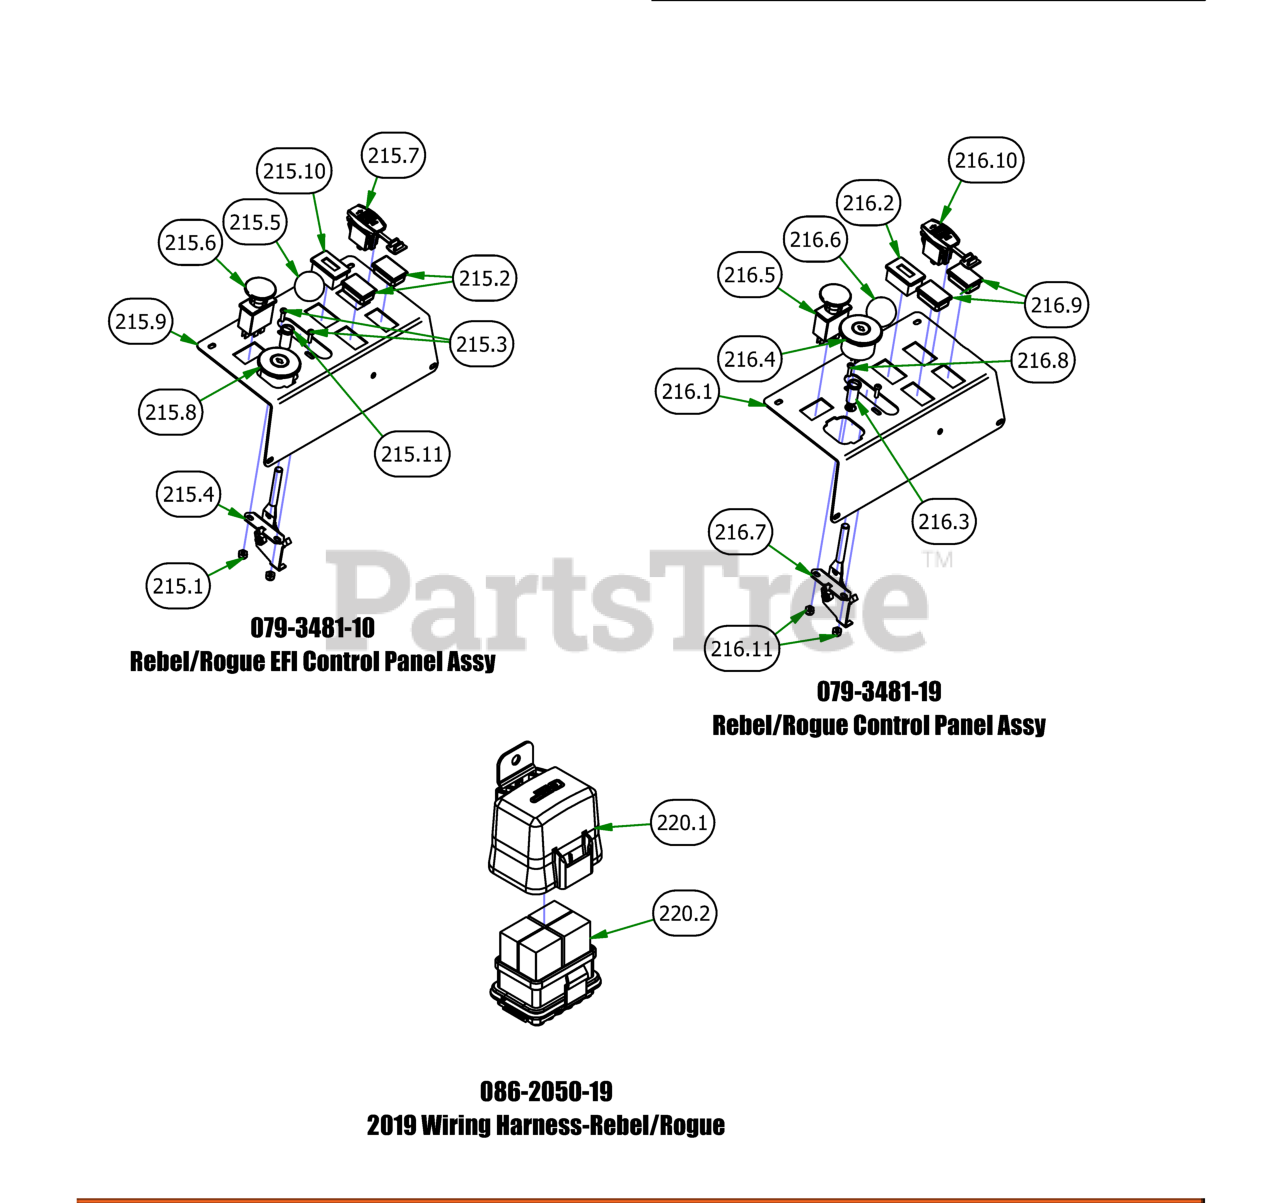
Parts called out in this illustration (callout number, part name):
215.1	10-24 Nylon Insert Locknut Zinc Orange Nylon
215.2	Light Plug
215.3	10-24 X 5/8 BS Button Head Bolt
215.4	Universal Throttle
215.5	Throttle Knob
215.6	PTO Switch
215.8	Ignition Switch
215.9	2019 Outlaw Control Panel
215.10	Tachometer
216.1	2019 Outlaw Control Panel
216.2	Tachometer
216.4	Ignition Switch
216.5	PTO Switch
216.6	Throttle Knob
216.7	Universal Throttle
216.8	10-24 X 5/8 BS Button Head Bolt
216.9	Light Plug
216.11	10-24 Nylon Insert Locknut Zinc Orange Nylon
220.1	Relay Block Cover Replacement Kit
